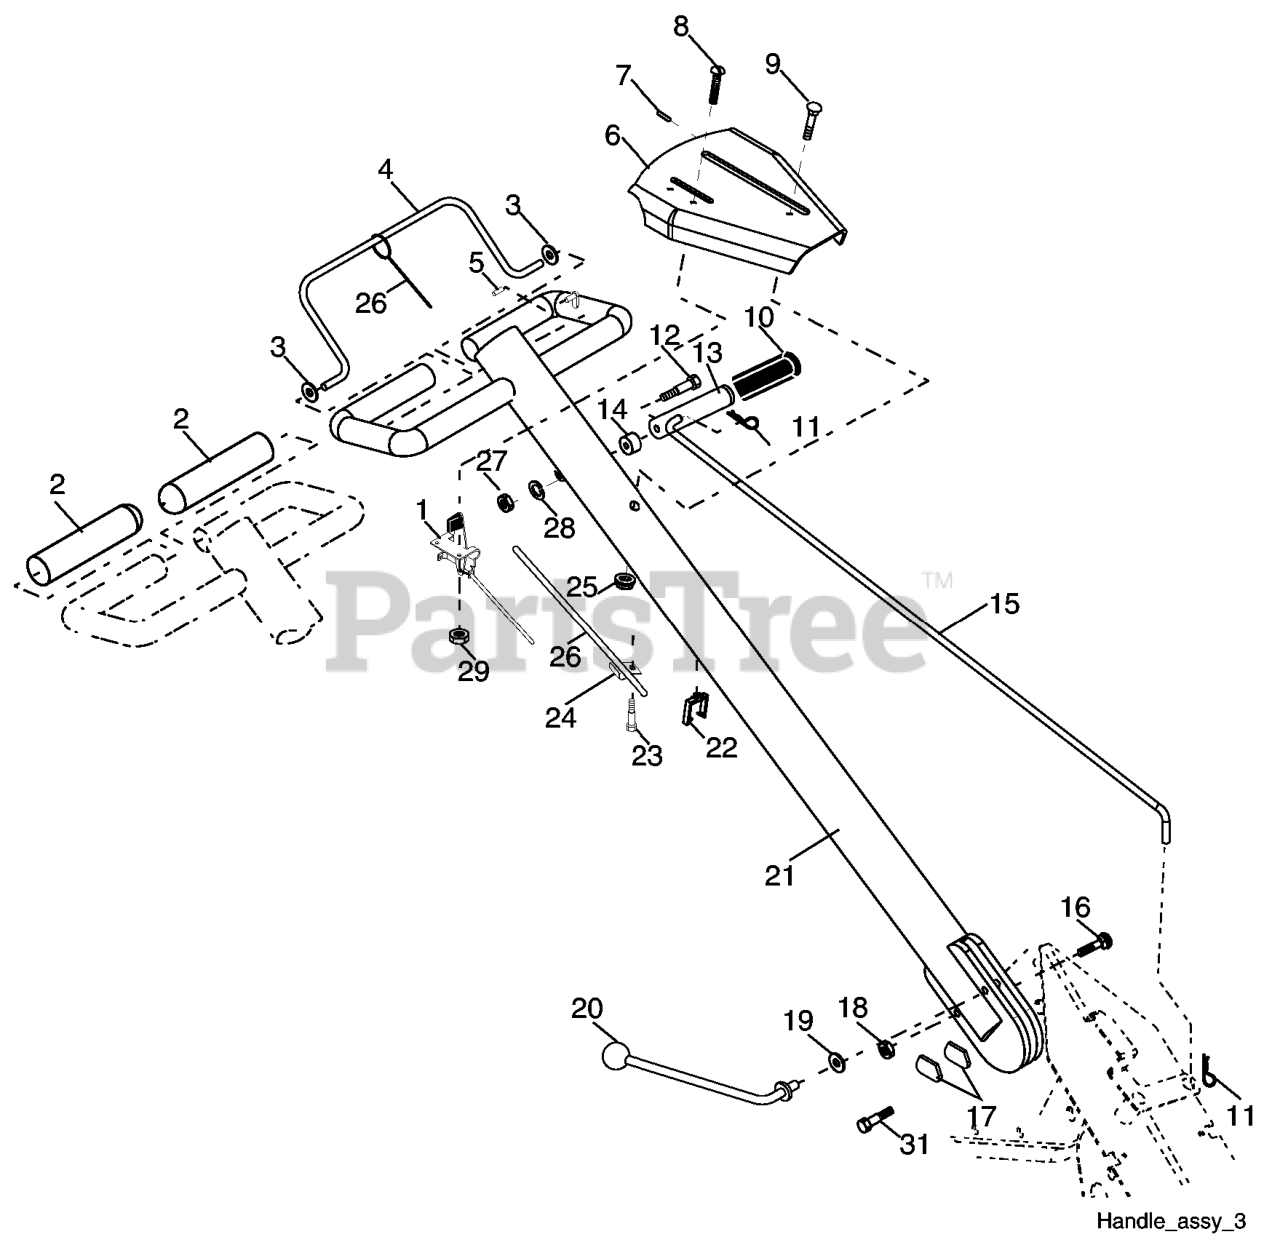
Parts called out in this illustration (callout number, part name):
1	THROTTLE.CONTROL.CRT.TILLER
2	GRIP.HANDLE.TILLER
3	GROMMET HANDLE
4	BAR ASSEMBLY, CONTROL
6	PANEL, CONTROL
7	BUSHING SPLIT
8	SCREW.PNHD.10-24
9	BOLT.5/16-18X2.5
10	GRIP, HANDLE
11	RETAINER M
12	SHOULDER BOLT ST
13	HANDLE, SHIFT
14	GROMMET.RUBBER.CRT.TILLER
15	ROD, SHIFT
16	BOLT D
17	LOCK.HANDLE.CRT
19	WASHER CRT
20	LEVER.LOCK.CRT
21	HANDLE
22	CLIP CABLE
23	TAPPING SCREW
24	CONDUIT.CLIP.PLATED
25	NUT.CENTERLOCK.5/16-
26	CABLE, CLUTCH
27	NUT T
29	NUT **
31	BOLT.PIVOT
